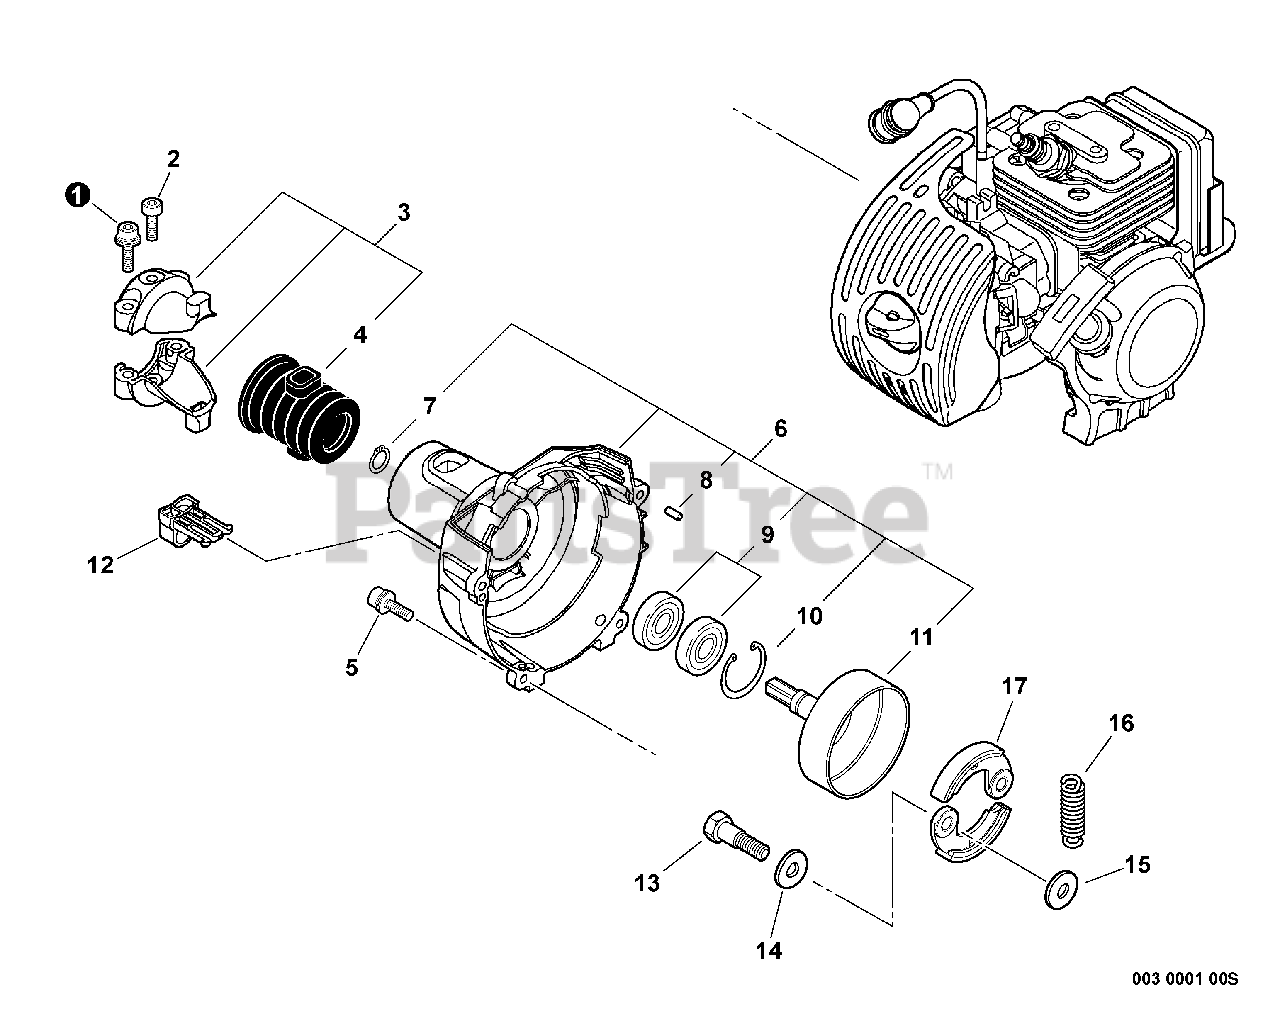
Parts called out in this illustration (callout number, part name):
1	SCREW - 5X25
2	SCREW - 5X12
3	MAIN PIPE CLAMP KIT
4	CUSHION
5	SCREW - 4X16
6	FAN CASE ASSY
7	RING, RETAINING - 12
8	PIN - LOCATING
9	BEARING, BALL - 6001
10	RING, RETAINING - 28
11	DRUM, CLUTCH
13	BOLT, CLUTCH
14	WASHER - SPRING
15	WASHER - 6
16	SPRING, CLUTCH
17	SHOE, CLUTCH
